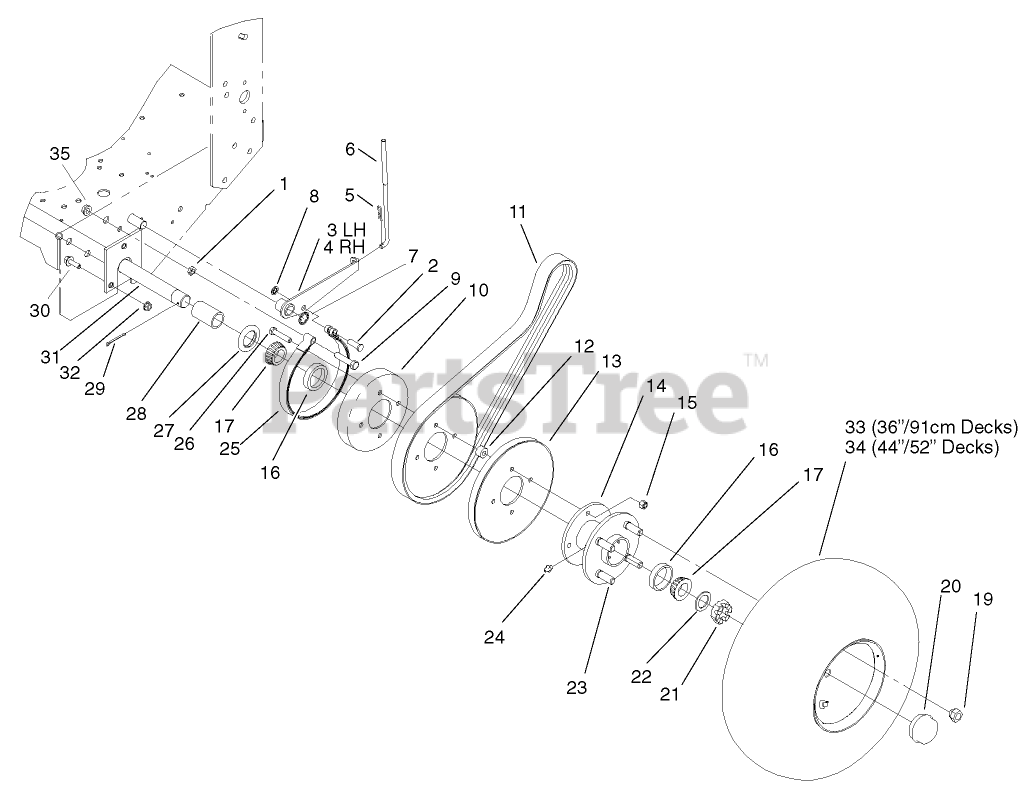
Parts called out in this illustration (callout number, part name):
1	NUT-JAM
2	PIN-CLEVIS
3	ARM-BRAKE, LH
4	ARM-BRAKE, RH
5	PIN-COTTER
6	ROD-BRAKE
7	RING-RETAINING
8	RING-RETAINING, EXTERNAL
9	SCREW-HH
10	DRUM-BRAKE
11	BELT-DRIVE, TRACTION
12	SPACER-PULLEY
13	PULLEY-WHEEL
14	HUB/WHEEL ASM
15	NUT-LOCK, NI
16	BEARING-CUP, TAPERED
17	BEARING-CONE, TAPERED
19	NUT-LUG
20	CAP-DUST
21	NUT-SHH
22	WASHER-SPACER
23	STUD-WHEEL
24	FITTING-GREASE
25	BAND-BRAKE
26	SCREW-HH
27	SEAL-GREASE
28	SPACER-WHEEL
29	PIN-COTTER
30	SCREW-HHF
31	AXLE ASM
32	NUT-HF
33	WHEEL AND TIRE ASM
34	WHEEL AND TIRE ASM
35	NUT-HHF, WHIZ
